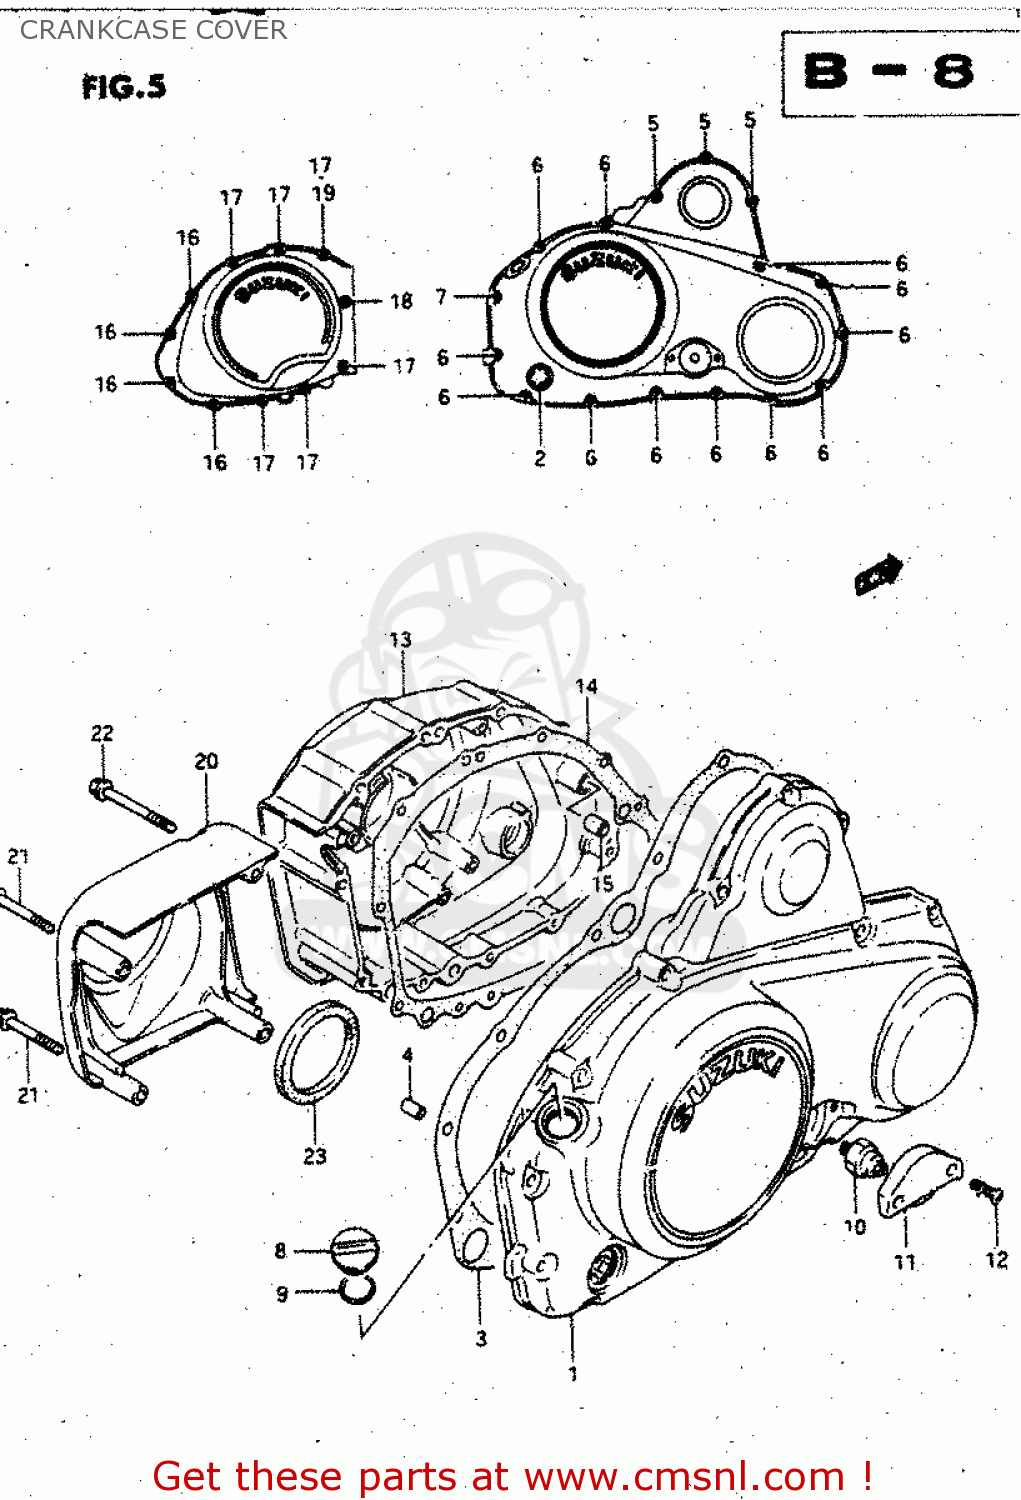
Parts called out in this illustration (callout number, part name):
1	COVER COMP,CLUTCH
2	LENS,OIL LEVEL CHECK
3	GASKET,CLUTCH COVER (MCA)
4	PIN
5	BOLT
6	BOLT
7	BOLT
8	Chrome Oil Fill Cap
9	O RING(D:3.1,ID:16.8)
10	SWITCH ASSEMBLY
11	CAP,OIL PRESSURE SWITCH
12	SCREW (L:20)(SUS)
13	COVER,GENERATOR
14	GASKET,MAGNETO COVER (MCA)
15	PIN (11X20)(SUS)
16	BOLT
17	BOLT
18	BOLT
19	GASKET(5.8X13X1.2) (NAS)
20	COVER,SECONDARY DRIVE
21	BOLT
22	BOLT
23	DAMPER,SECONDARY COVER
